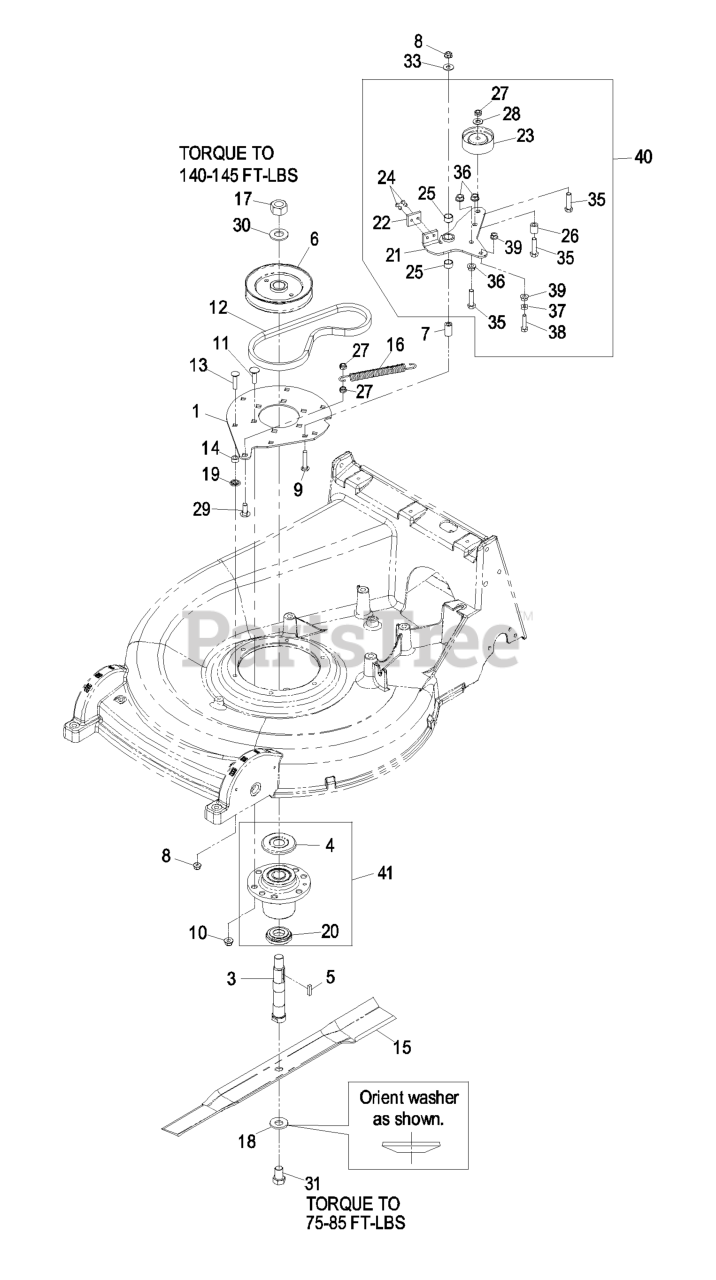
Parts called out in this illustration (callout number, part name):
1	PLATE-ADAPTER, HOUSING
3	SHAFT-SPINDLE
4	GUARD-BEARING, TOP
5	KEY-RECTANGLE
6	SHEAVE-SPLIT, STEEL (W/HU
7	BUSHING-ARM, IDLER
8	NUT-HF, NI
9	SCREW-CARR
10	NUT-HF, NI
11	Bolt-Carriage 3/8-16 X 1 1/4
12	BELT
13	BOLT-CARR
14	SPACER
16	SPRING-BRAKE
18	WASHER-SPRING
19	RING-RETAINING
20	SPACER-GUARD, BOTTOM
21	ASM,IDLER ARM W/BSHGS
22	PAD-BRAKE
23	PULLEY-IDLER
24	RIVET-POP
25	BEARING
26	BUSHING-LEVER, LIFT
28	WASHER-FLAT
29	SCREW-CARR
31	SCREW-CAP
33	WASHER-FLAT
35	SCREW-HH
36	NUT-HHF, WHIZ
37	NUT-JAM
38	SCREW-HH
40	IDLER ARM ASM
41	KIT, CUTTER HOUSING
42	ASM,CUTTER HOUSING COMPLE
